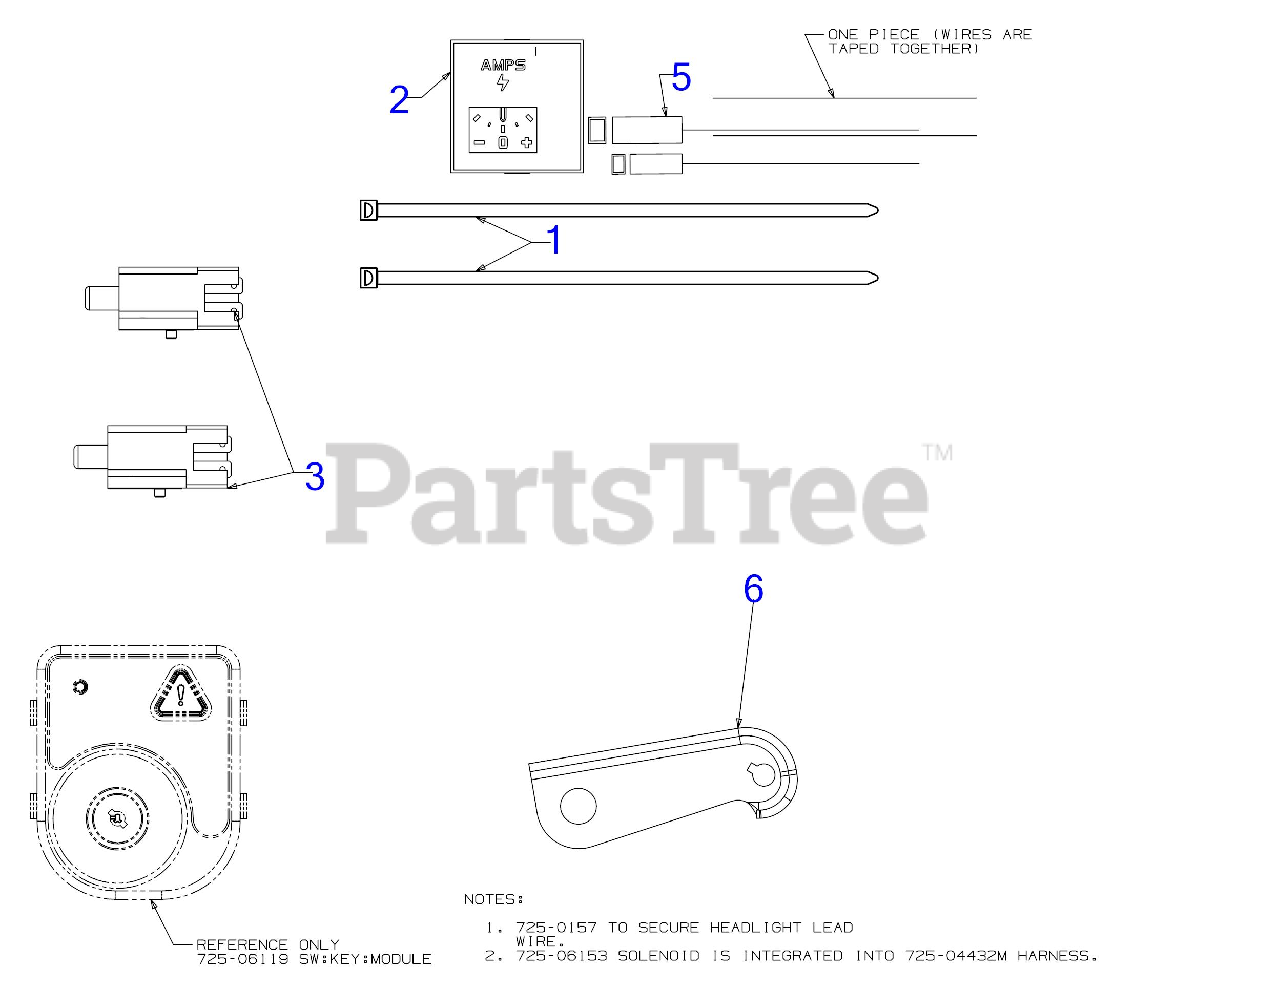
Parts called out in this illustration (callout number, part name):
1	7" CABLE TIE
2	INDICATOR MONITOR
3	INTERLOCK SWITCH (NO/NC)
5	JUMPER HARNESS ASSEMBLY
6	LATCH SPEED BRACKET
